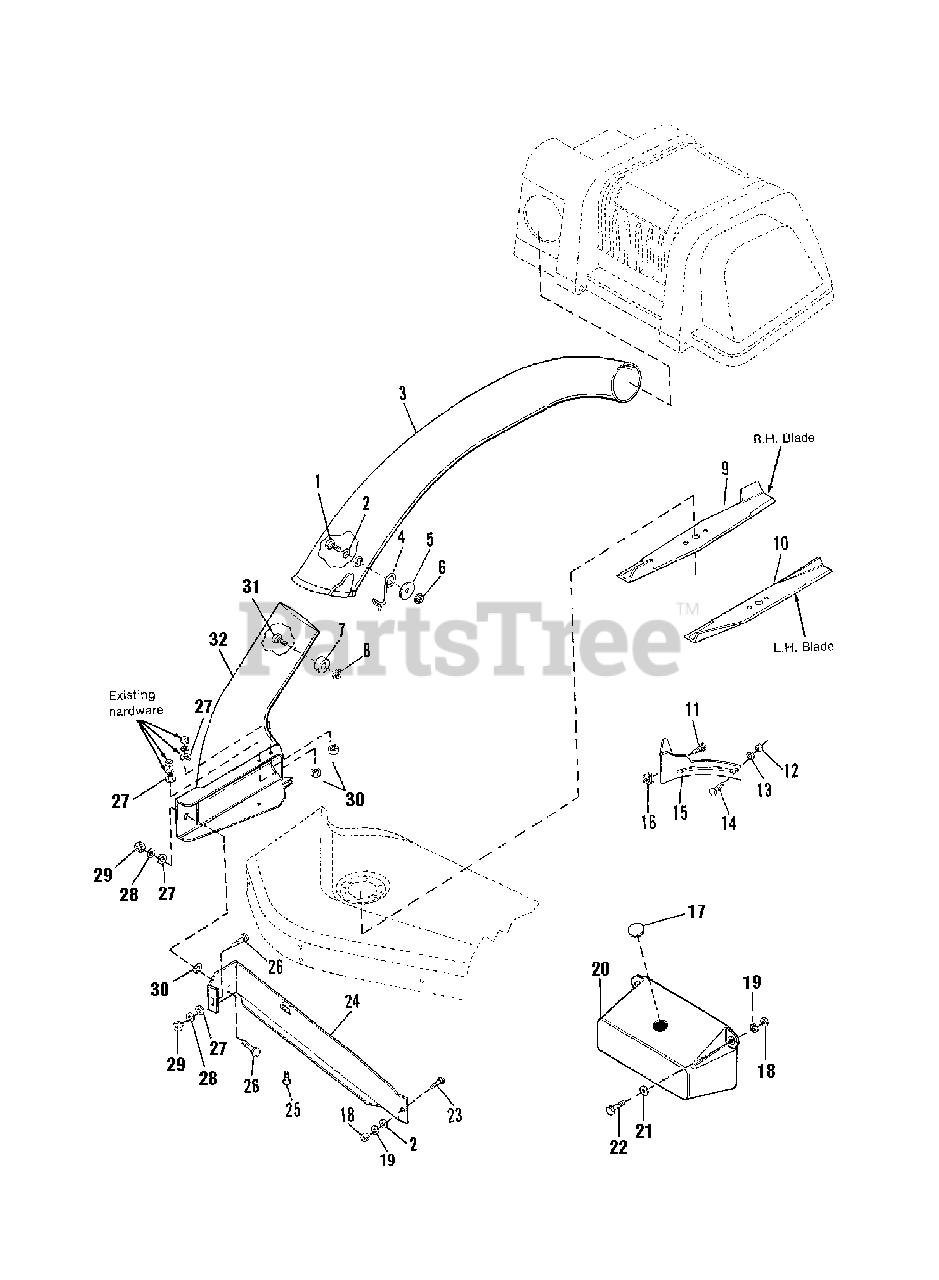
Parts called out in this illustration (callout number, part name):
1	CAPSCREW, Hex Head, 5/16-18 x 3/4
2	WASHER, Flat, 5/16
3	TRANSFER TUBE
4	LATCH, Tube
5	WASHER, Flat
6	NUT, Flange Lock, 3/8
7	WASHER, Special
8	NUT, Esna, Hex Lock, 5/16-18
9	BLADE, R.H.
10	BLADE, L.H.
11	CAPSCREW, Whizlock, 1/4-20 x 1/2
12	NUT, Hex, 1/4-20
13	LOCKWASHER, 1/4
14	CARRIAGE BOLT, 1/4-20 x 5/8
15	BAFFLE, Deflector Side
16	NUT, Retainer, 1/4-20
18	NUT, Hex, 5/16-18
19	LOCKWASHER, 5/16
20	COUNTERWEIGHT
21	WASHER, Plain
22	CAPSCREW, Hex Head, 5/16-18 x 1
23	CARRIAGE BOLT, 5/16-18 x 7/8
24	BAFFLE ASSEMBLY, Discharge
25	CAPSCREW, Taptite, 5/16-18 x 1/2
26	CARRIAGE BOLT, 3/8-16 x 3/4
27	WASHER, Flat, 3/8
28	LOCKWASHER, 3/8
29	NUT, Hex, 3/8-16
30	NUT, Push, 3/8
31	CAPSCREW, Hex Head, 5/16-18 x 3/4
